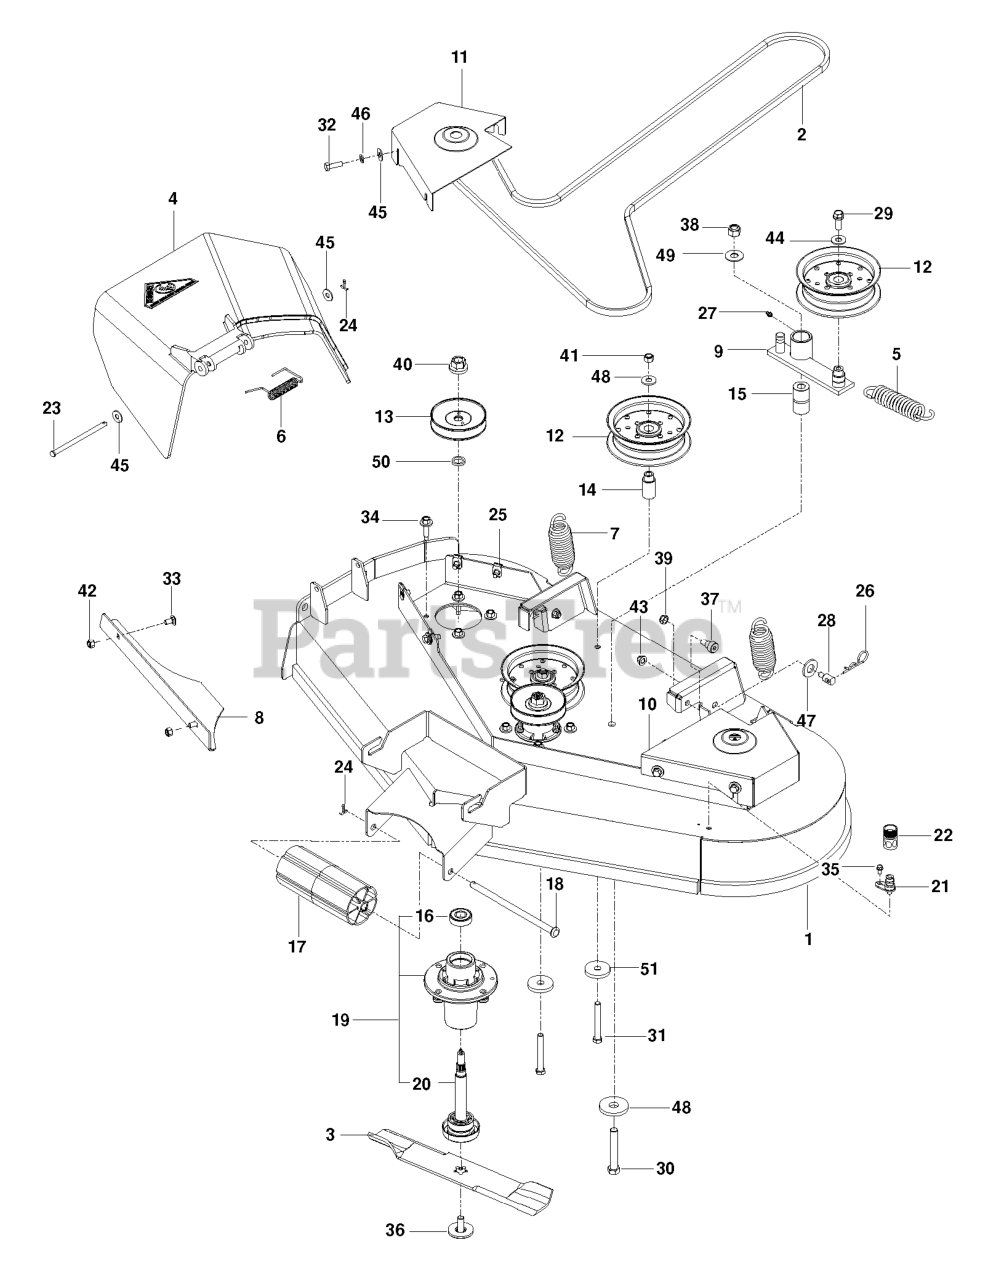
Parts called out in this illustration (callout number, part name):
5	BRAKE WIRE
35	REAR AXLE REAR AXLE WELDED FOR
71	LEVER
79	CASE.TOP.GRAY
83	LIFTING LEVER ASSY FOR REAR AX
90	PULLEY.CAM.DRIVE.CONTROL.HV
91	CASE BOTTOM
92	BRACKET, DRIVE CONTROL
93	SCREW, PHILLIPS HEAD 10 X 5/8
